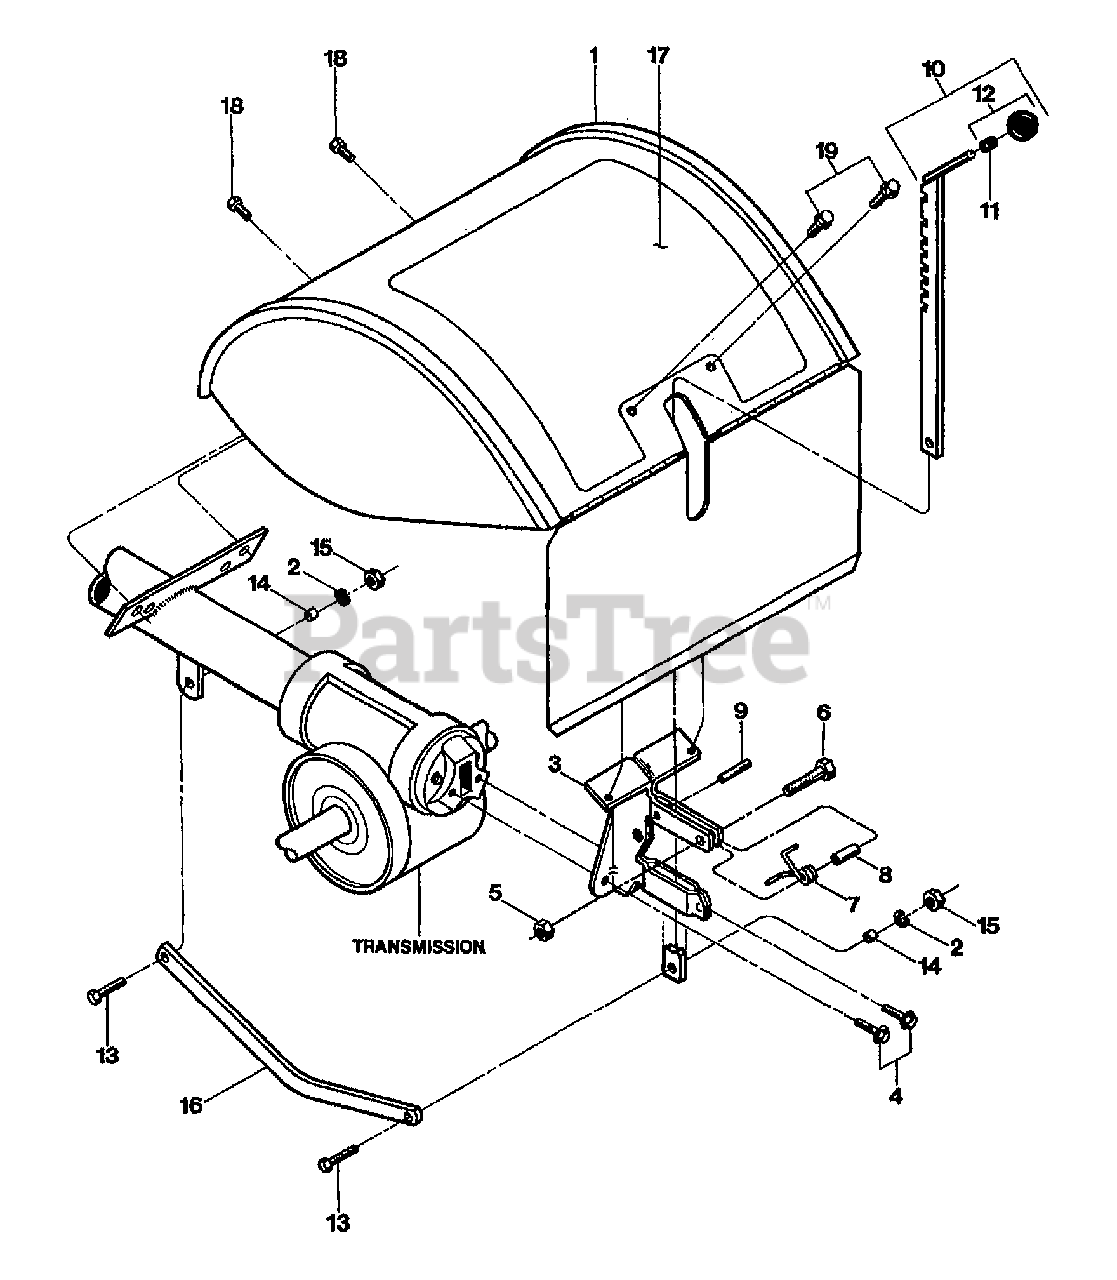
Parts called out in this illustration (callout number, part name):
1	HOOD W/DECAL ECONO OPC (INCL. 17)
2	WASHER-LK .375 @ DEPL
3	BRKT W/ROLL PIN (9308) (INCL. 9)
4	SCR-HFLK 5/16-18X.75 ZP
5	NUT-LK 1/4-20
6	SCR-HH 1/4-20X1.0
7	SPRING-TORSION
8	SPACER-.250X.343X.375
9	PIN-ROLL .25 X 1 (SPIRAL)
10	DEPTH REGULATOR W/KNOB (INCL. 11 & 12)
11	RING-TOLERANCE .5325 ID
12	KNOB-CONTROL (INCL. 11)
13	SCR-HH 3/8-16X1.25
14	BUSHING-.5X.375X.3
15	NUT-HEX 3/8-16 ZP
16	DRAG BAR-BENT
17	DECAL-HOOD OPER INST
18	SCR-HWH 5/16-18 X .5 STH
19	SCR-HWH 1/4-20 X .5 STH
